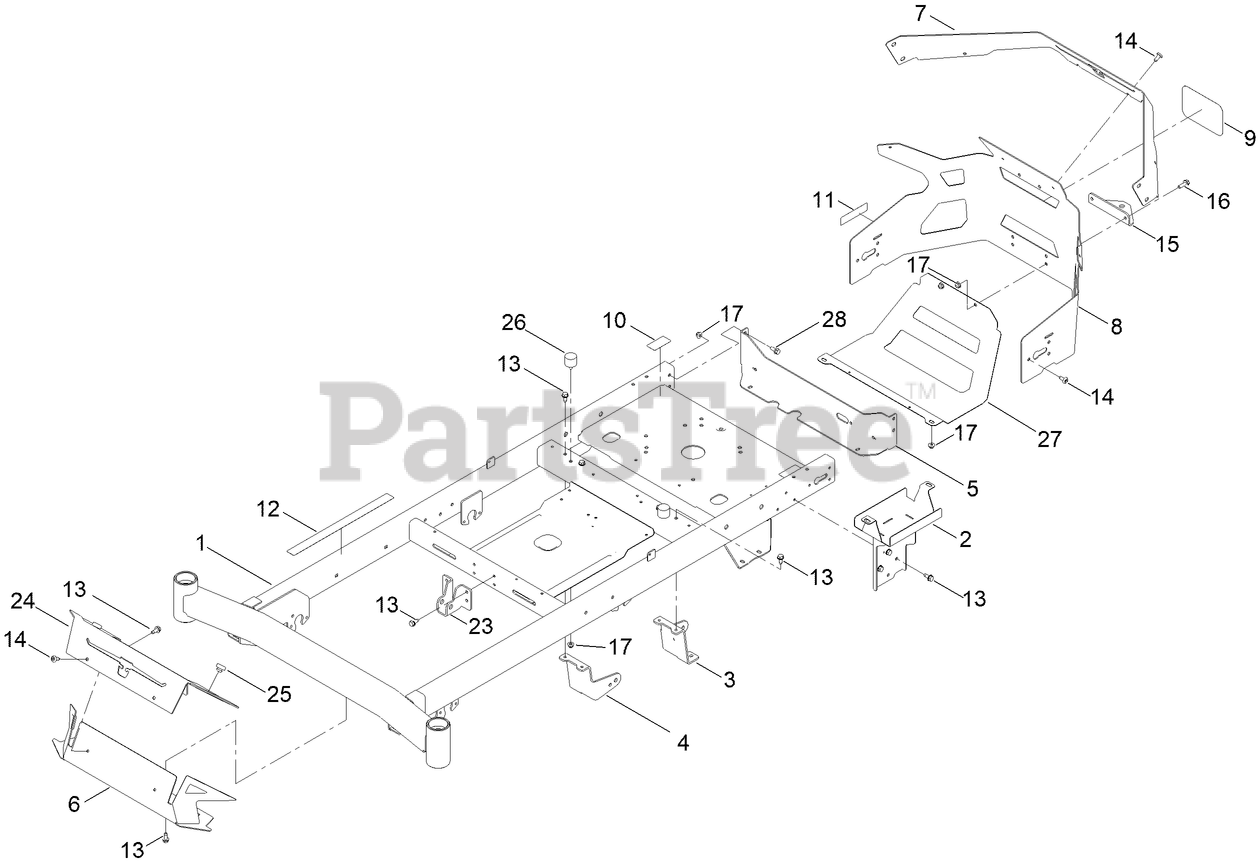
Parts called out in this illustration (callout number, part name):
1	SERVICE ASM-FRAME, TC
2	WA-BATTERY MOUNT
3	MOUNT-DRIVE, LH
4	MOUNT-DRIVE, RH
5	PLATE-MOUNT
6	FOOTREST-TOP
7	PLATE-REAR CLADDING TC
8	GUARD-ENGINE TC
9	DECAL
10	DECAL-BYPASS
11	DECAL-SPARK ARRESTER
12	DECAL-WARNING
13	SCREW-HWHTF
15	BRACKET-HITCH
16	SCREW-HHF
17	NUT-HF
23	BRACKET-MOUNT DAMPER, LOWER
24	PLATE-KICK, MR
25	BUMPER-RUBBER
26	BUMPER-RUBBER
27	GUARD-MUFFLER [BLACK]
28	SCREW-HHF
